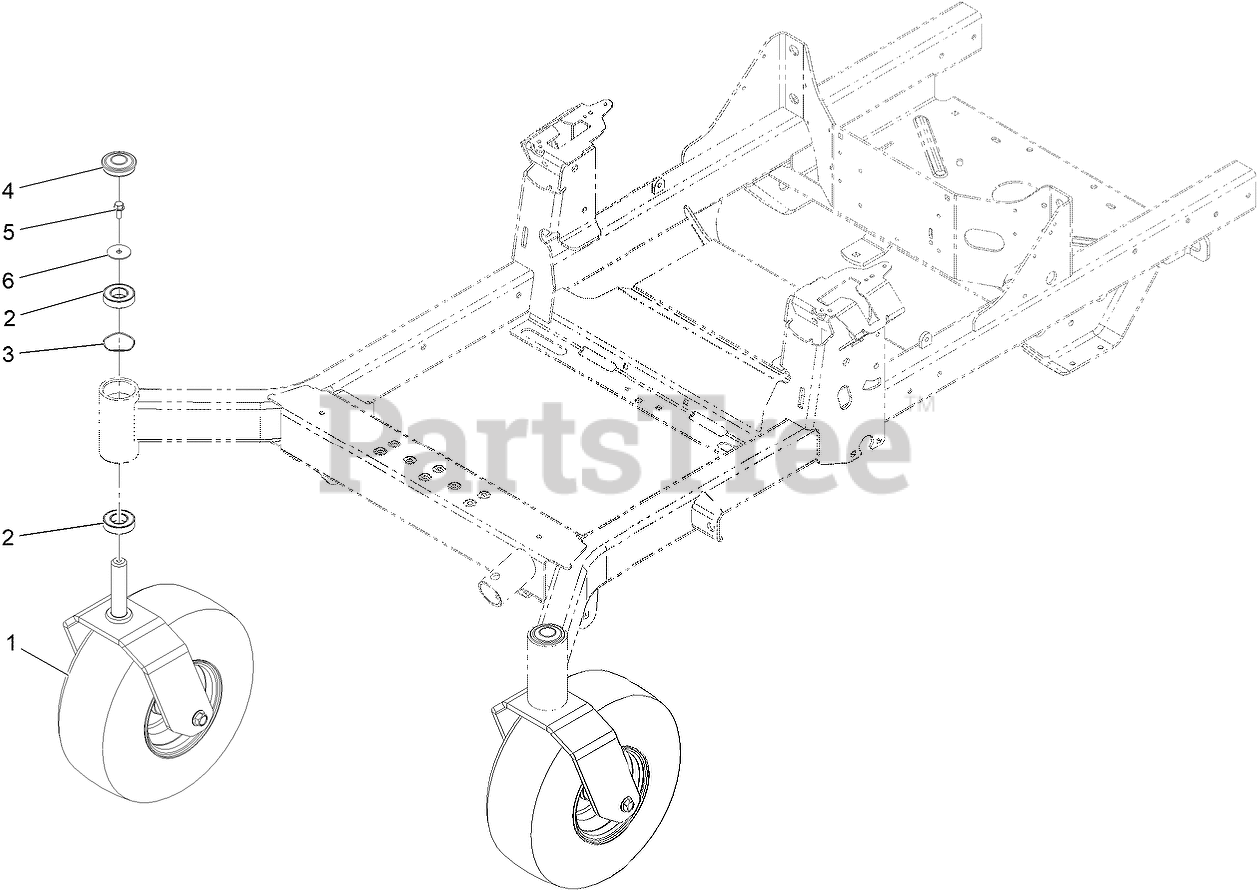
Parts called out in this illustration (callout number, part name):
1	ASM-Front Caster
2	BEARING-BALL
4	CAP-GREASE
5	SCREW-HHF
6	WASHER-FLAT
